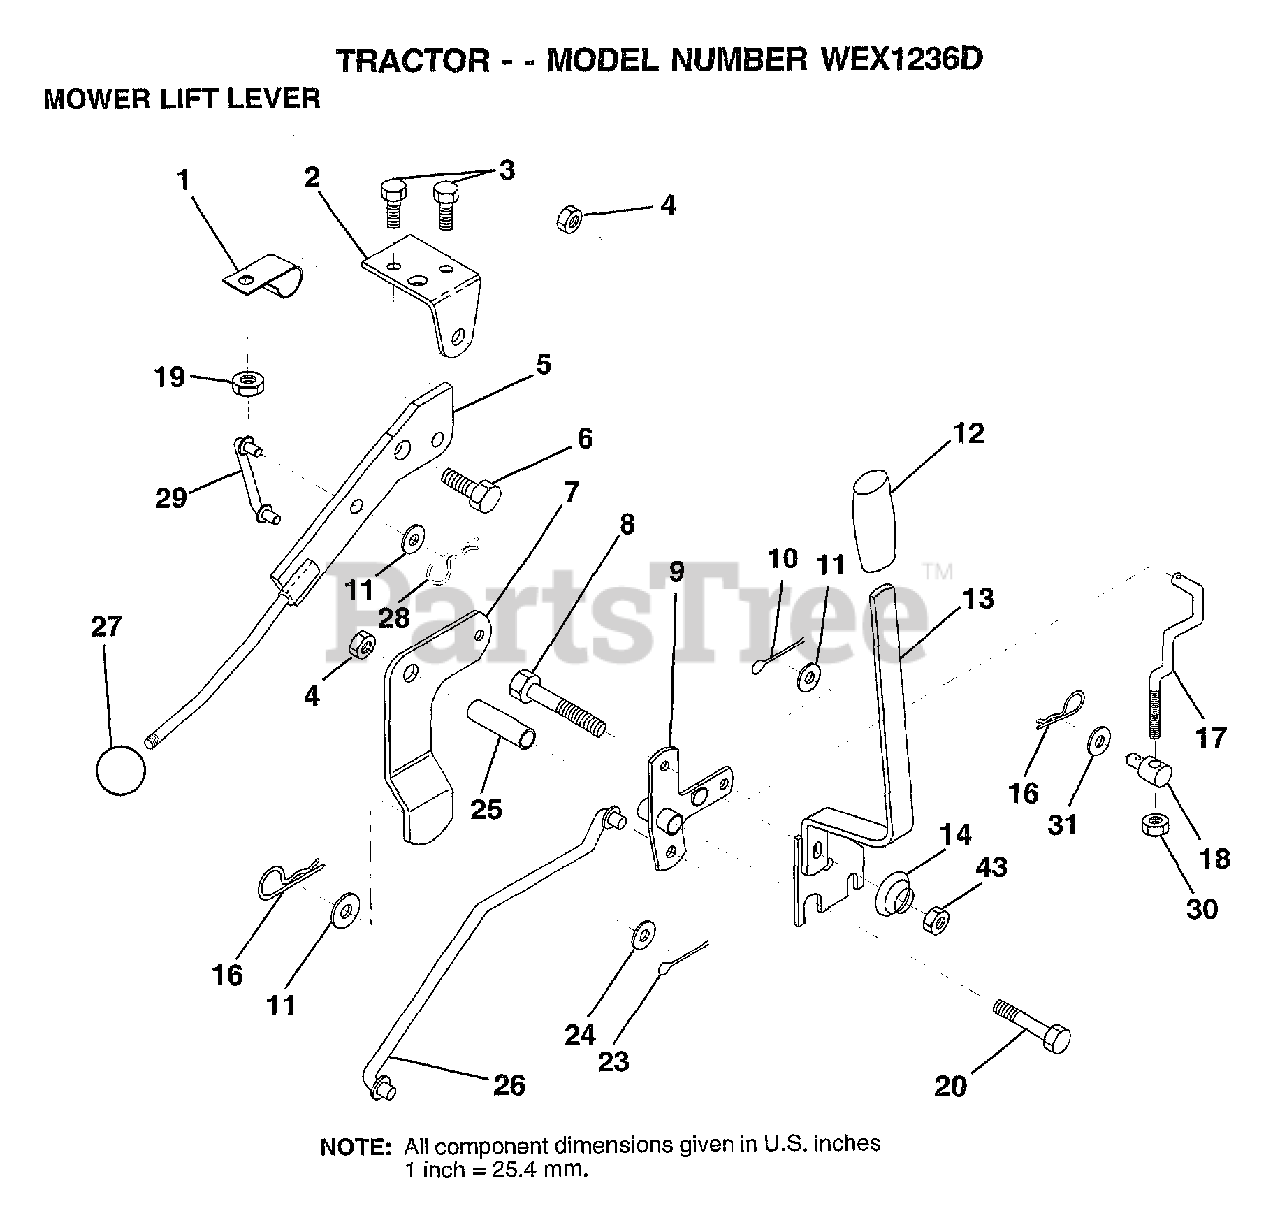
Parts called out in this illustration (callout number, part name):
1	"CLIP,INSULATOR"
2	BRKT CLUTCH
3	BOLT HXHD FIN
5	LEVER.ASM.CLUTCH
6	"BOLT, SHOULDER LT"
7	MWR CLUTCH ARM AS
8	BOLT
9	"BELLCRANK,LIFT"
10	COTTER PIN
11	WASHER
13	HANDLE.ASM.LIFT
14	SPRING COMPRESSIO
16	SPRING.RETAINER
17	"LINK,LIFT FRT"
18	TRUNION ADJ
20	BOLT
23	PIN COTTER 1/8
25	TUBE SPACER
26	ROD LIFT MOWER
27	KNOB T(3/8 HOLE)
28	RETAINER M
29	CLUTCH LINK
30	NUT
31	WASHER
